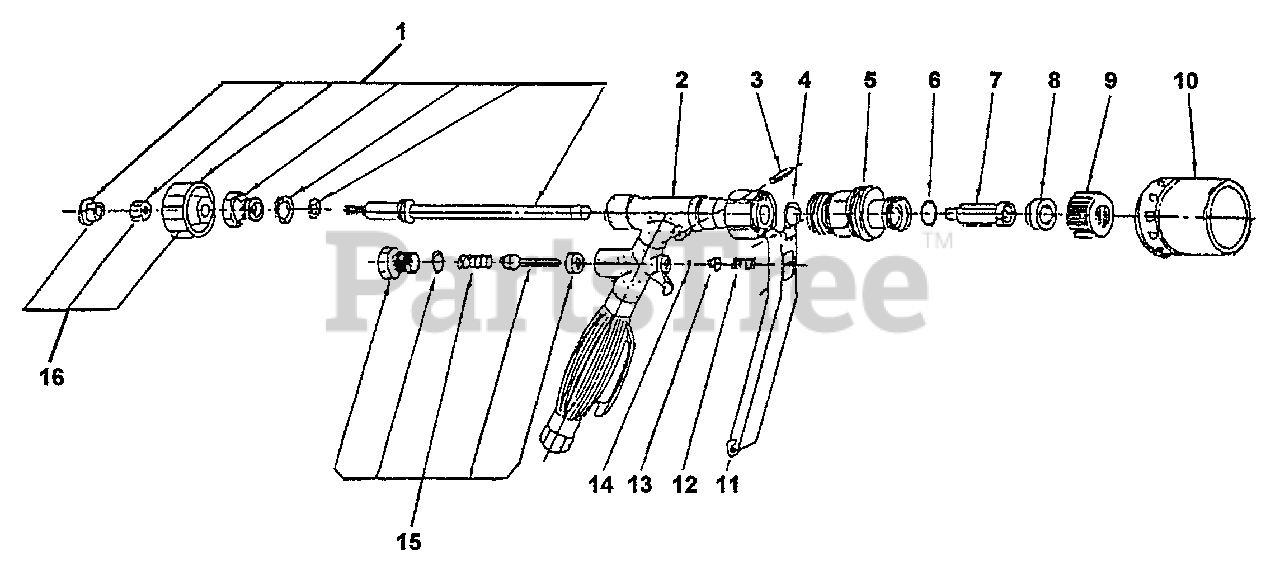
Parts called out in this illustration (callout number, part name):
1	VALVE SHAFT ASSY
2	BODY, GUN
3	PIN - SPRING -- 4X20
4	O-RING - 11
5	HOLDER, VALVE
6	O-RING - 12
7	CORE, ZOOM
8	NOZZLE, PLATE
9	CAP
12	SPRING, LEVER
14	O-RING - 3
15	VALVE SHAFT ASSY
16	KNOB
